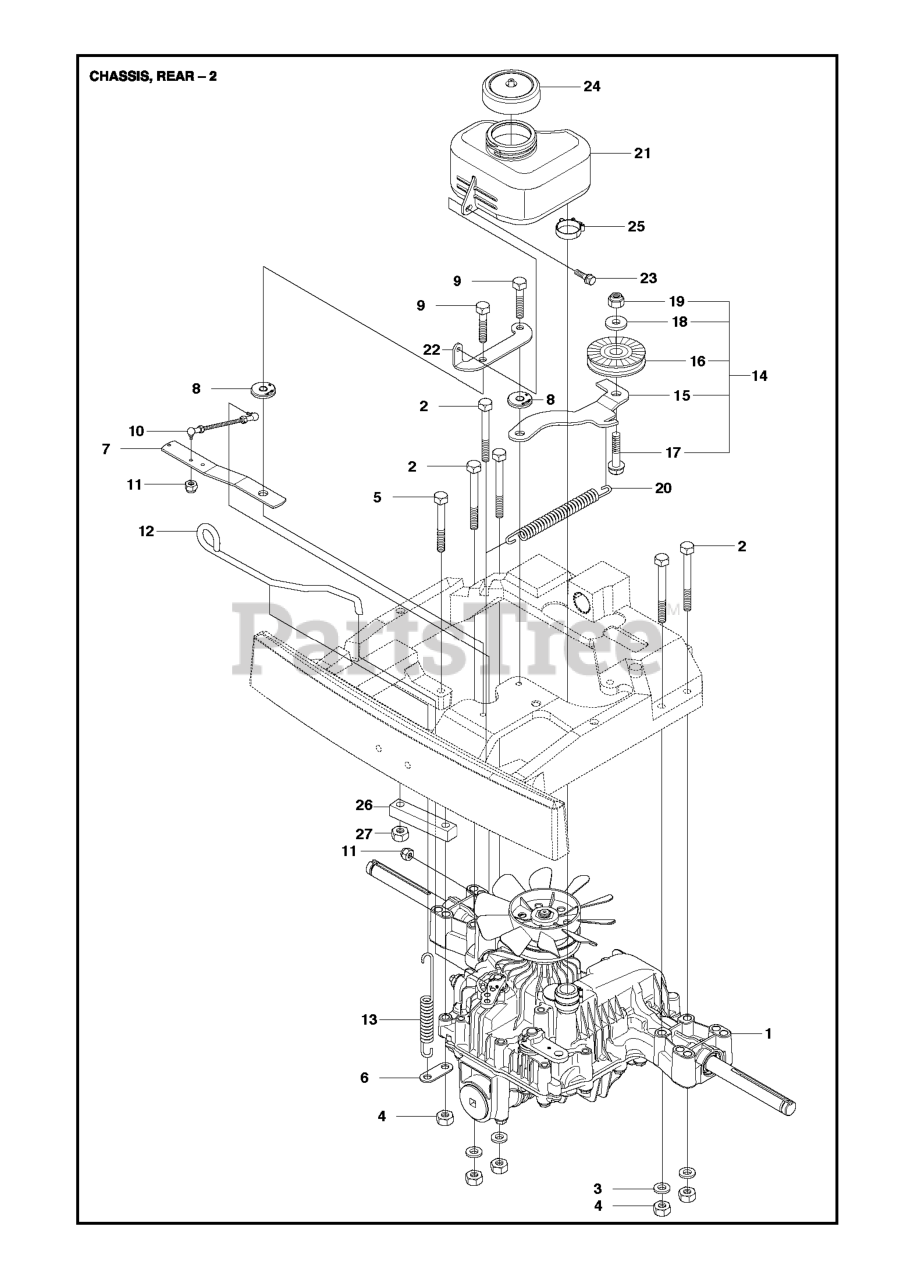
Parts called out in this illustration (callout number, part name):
1	TRANSMISSION K574A
3	WASHER BRB 8.4X17
4	NUT
5	SCREW
8	Washers
8	WASHER
9	SCREW
11	LOCKNUT M5
15	BELT TENSIONER ARM
19	LOCKNUT M8
25	HOSE CLAMP 20-32
26	BRACKET
27	NUT
